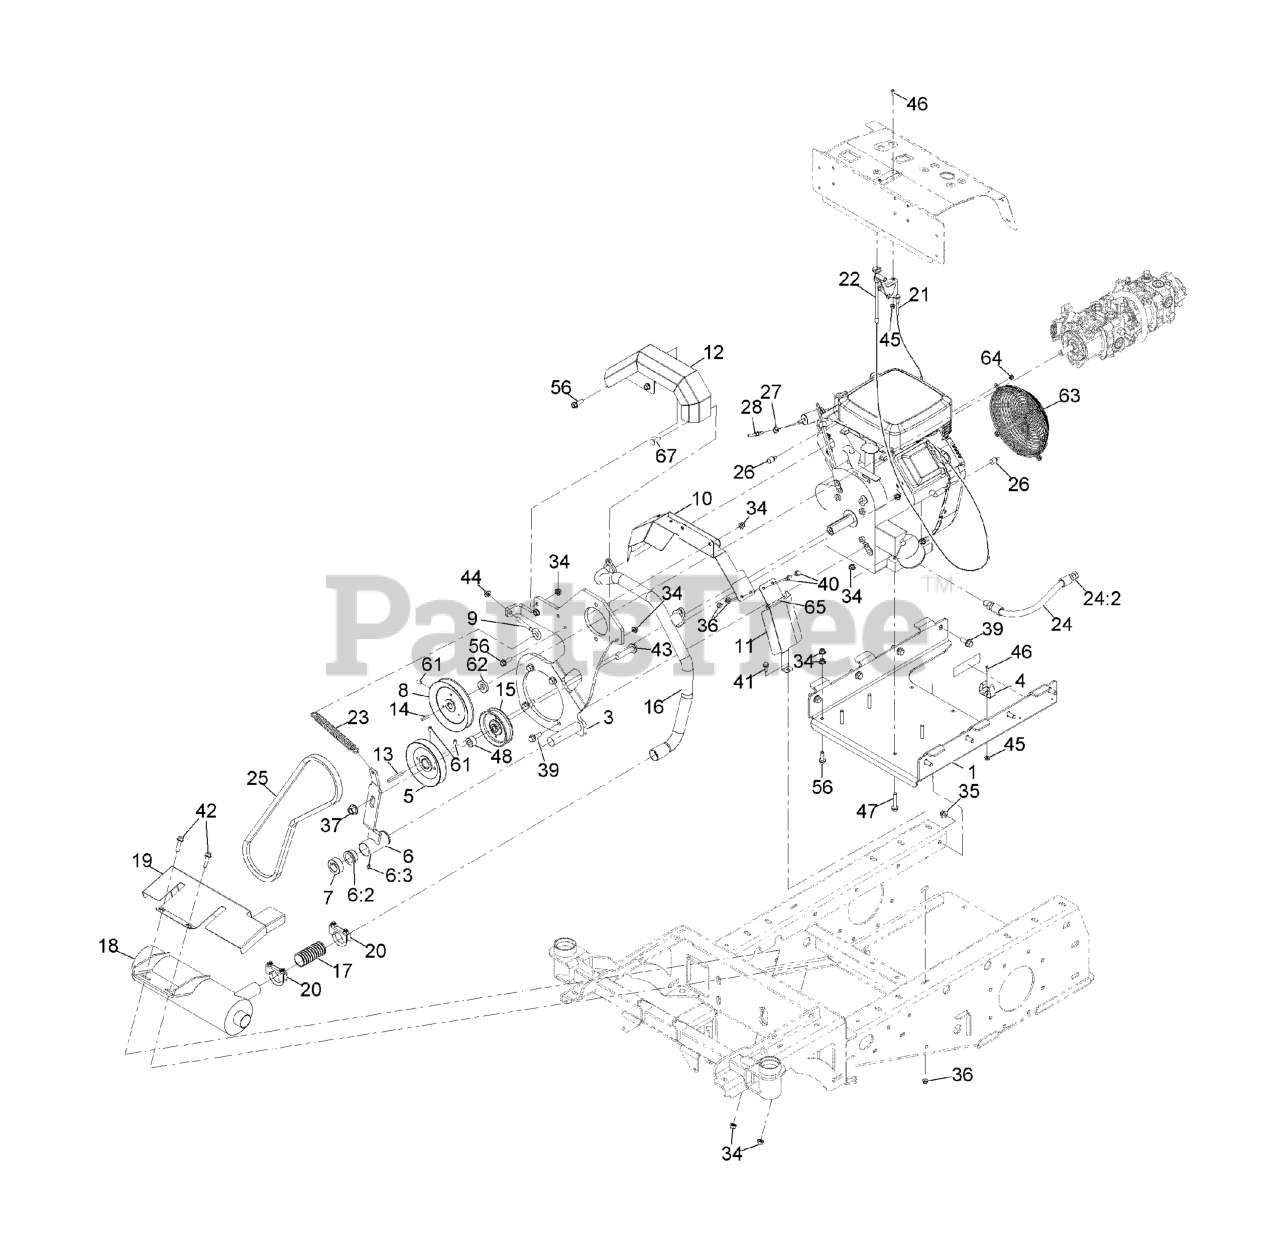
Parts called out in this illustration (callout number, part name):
1	Tray-Engine
3	Bracket-Engine, Pump [black]
4	Holder-Tool, Clip
5	PULLEY-DRIVE
6	Arm-Tension, ASM
6:2	BUSHING-FLANGE
6:3	FITTING-GREASE, ZERK
8	PULLEY-DRIVE, PUMP
9	Bolt-Eye
10	Guard, Lower Muffler
11	Guard, Lower Muffler
12	Guard-Pulley
15	PULLEY-IDLER, FLAT
16	Manifold-Exhaust
17	TUBE-EXHAUST, FLEX
18	MUFFLER
19	SHIELD-HEAT, MUFFLER
20	Clamp-Muffler
21	CABLE-THROTTLE
22	CABLE-CHOKE
23	SPRING-EXTENSION
24	ASM, Oil Drain Hose W/Plug
26	Tube-Heat Shrink, 1/2
27	CLAMP-HOSE
28	BARB-FUEL
34	Nut-Hex Flange
35	Nut-Hex Flange
36	Nut-Hex Flange
37	Nut-Lock 1/2-13
39	SCREW-HHF
40	SCREW-HHF
41	Screw-HHF
42	SCREW-HHF
43	Screw-HHF
44	NUT-HF, NI
45	Nut-Hex Flange
46	Screw-HSBH
47	Screw-HHF
56	SCREW-HHF
61	Setscrew-HSH
63	GUARD-WIRE, VANGUARD
65	TIE-CABLE
67	Bolt,Carriage,5/16-18X1,ST/ST 18-8
